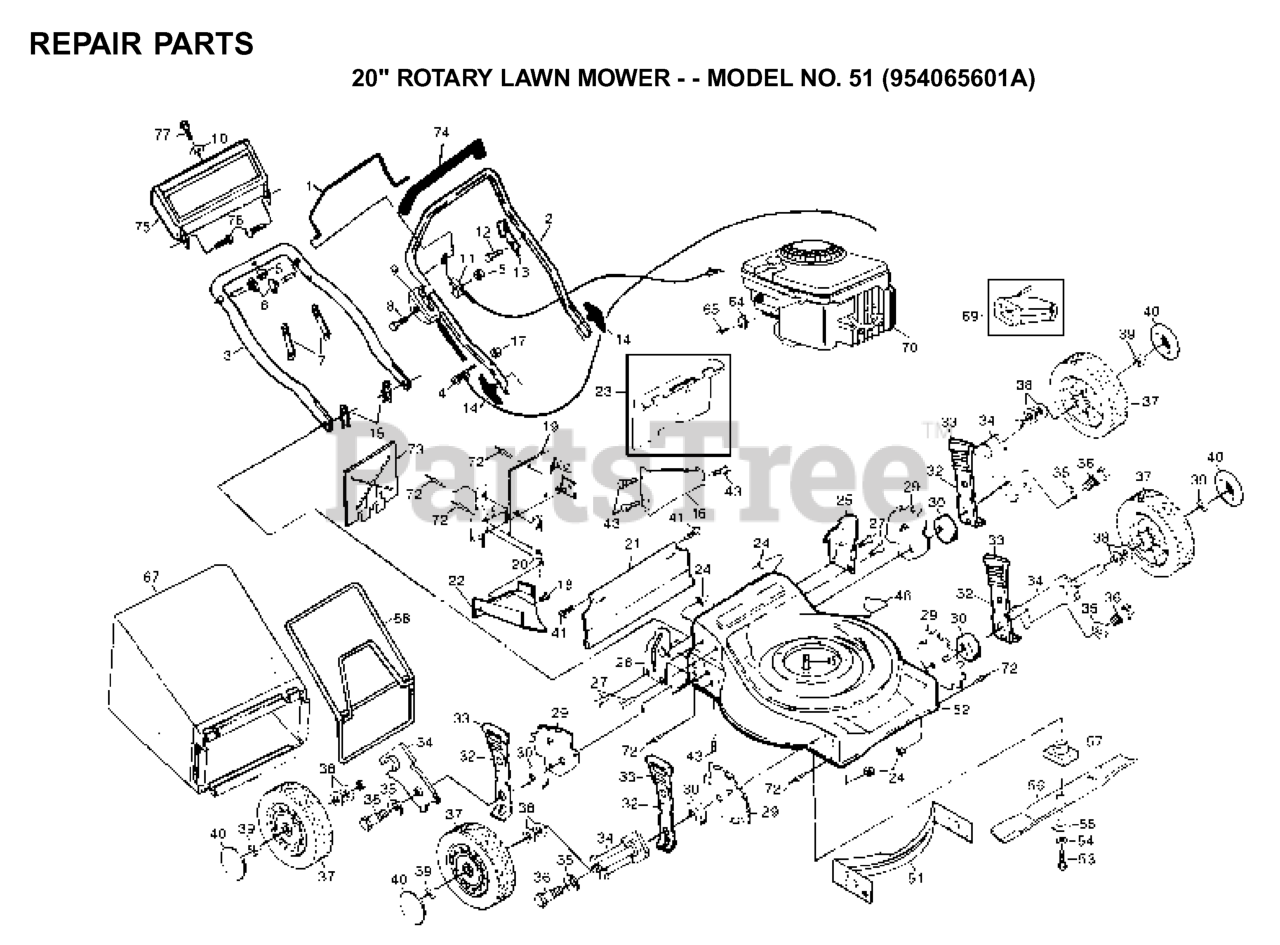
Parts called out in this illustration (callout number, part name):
1	CONTROL BAR/BLACK
2	UPPER HANDLE
3	HANDLE, LOWER PM
4	ROPE GUIDE
5	NUT
6	HANDLE BOLT
7	TIE GUIDE
8	SCREW 1/4-20 X 2.12
11	CABLE.MZR.51.RT.SP./PU.
12	TAPPING SCREW
13	BRACKET UPSTOP
14	HANDLE KNOB
15	HAIRPIN COTTER
16	REAR BAFFLE
17	NUT
19	BACK PLATE
20	SIDE BAFFLE
21	REAR SKIRT
22	DISCHARGE BAFFLE
23	REAR DOOR KIT
24	LOCKNUT PM
27	SCREW
29	WHEEL ADJUST BRACKET
30	SPACER PM
32	SELECTOR SPRING
33	SELECTOR KNOB
34	AXLE ARM AS PM
35	WASHER.BELLEVILLE (3 2 LB)
36	BOLT
37	WHL & TIRE ASSEMBLY
38	WAVE WASHER
39	HEX FLANGE LOCKNT
41	HINGE SCREW
45	BOLT
46	DECAL HYT
51	FRONT BAFFLE
52	HOUSING ASSY
53	SCREW, HEX HD 3/8-24 X 1-3/8
54	LOCKWASHER
55	WASHER,HARDEN
56	BLADE 20" MULCH
57	BLADE ADAPTOR
65	SCREW.HEX.HEAD.WASHER.10-16
67	GRASS BAG
68	CATCHER.FRAME.WALK
72	RIVET BLIND
74	HANDLE GRIP
75	TRIM PLATE
77	SCREW
